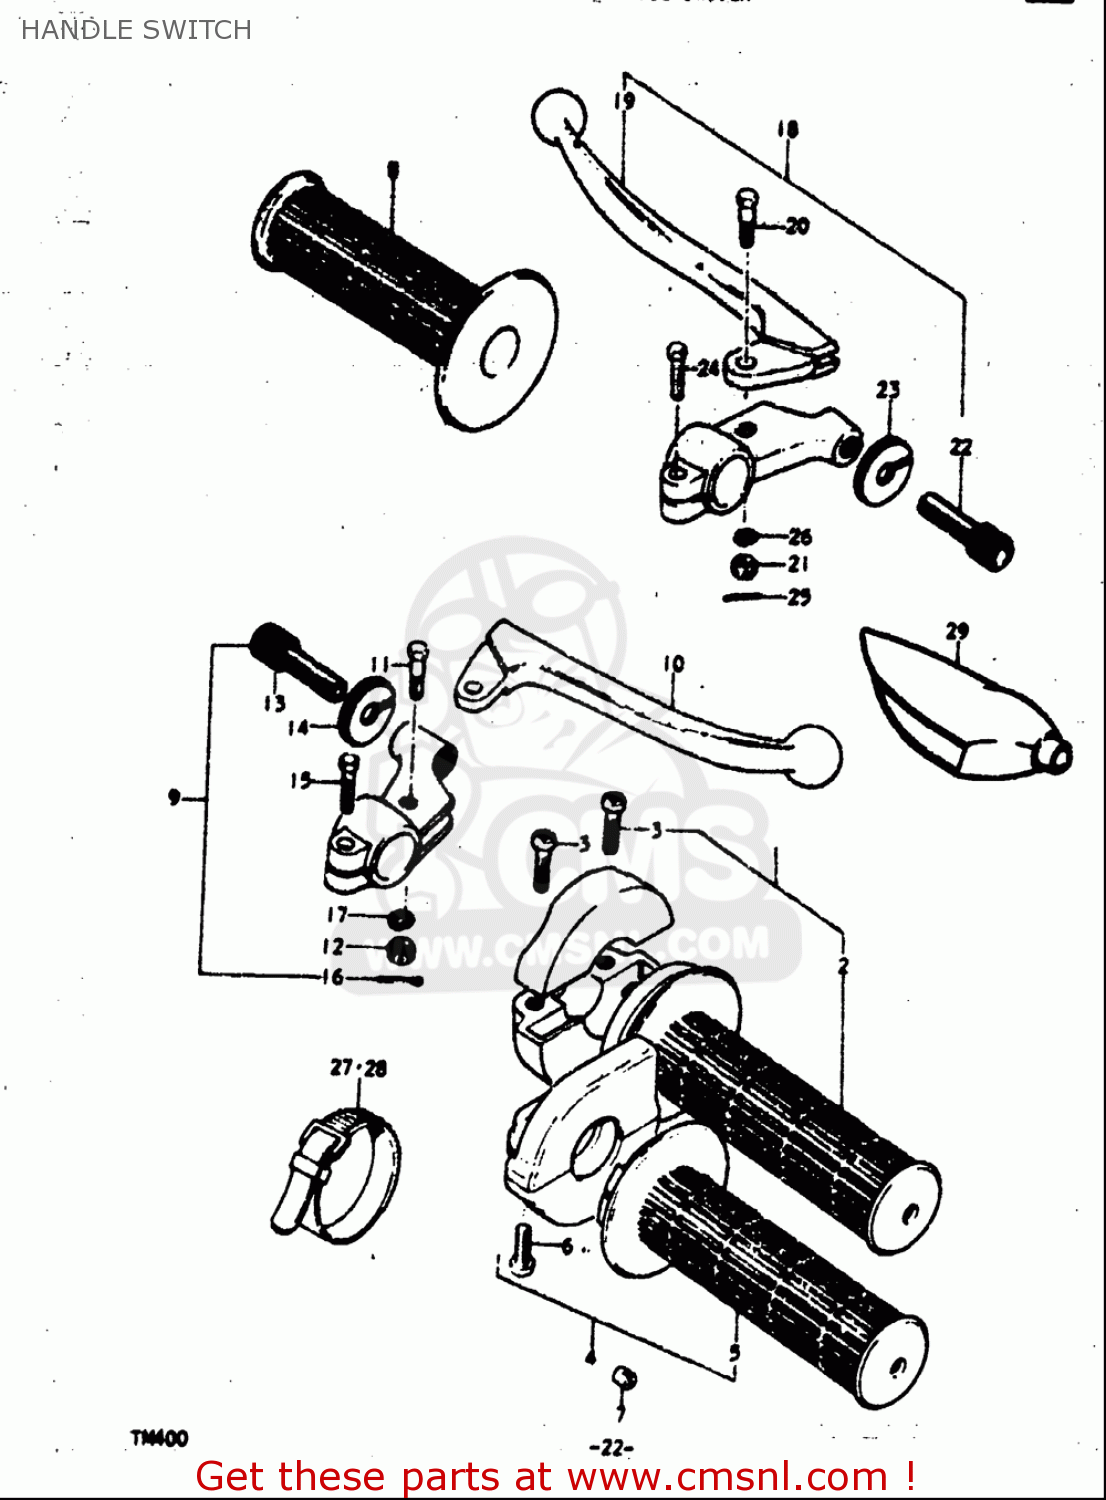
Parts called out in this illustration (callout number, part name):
3	SCREW
6	SCREW
7	PIECE,THROTTLE END
9	BRAKE LEVER & SWITCH ASSY
10	LEVER,BRAKE
11	BOLT,LEVER PIVOT
12	NUT,LEVER FITTNG
13	ADJUSTER,CABLE
14	NUT,CABLE ADJUSTER
15	BOLT
16	PIN 16X20
17	WASHER,LOCK
18	LEVER ASSY,CLUTCH
19	LEVER,CLUTCH
20	BOLT
21	NUT,LEVER FITTNG
22	ADJUSTER,CABLE
23	NUT,CABLE ADJUSTER
24	BOLT
25	PIN 16X20
26	WASHER,LOCK
27	CLAMP(L:120)
28	CLAMP
29	COVER,CLUTCH LEVER
